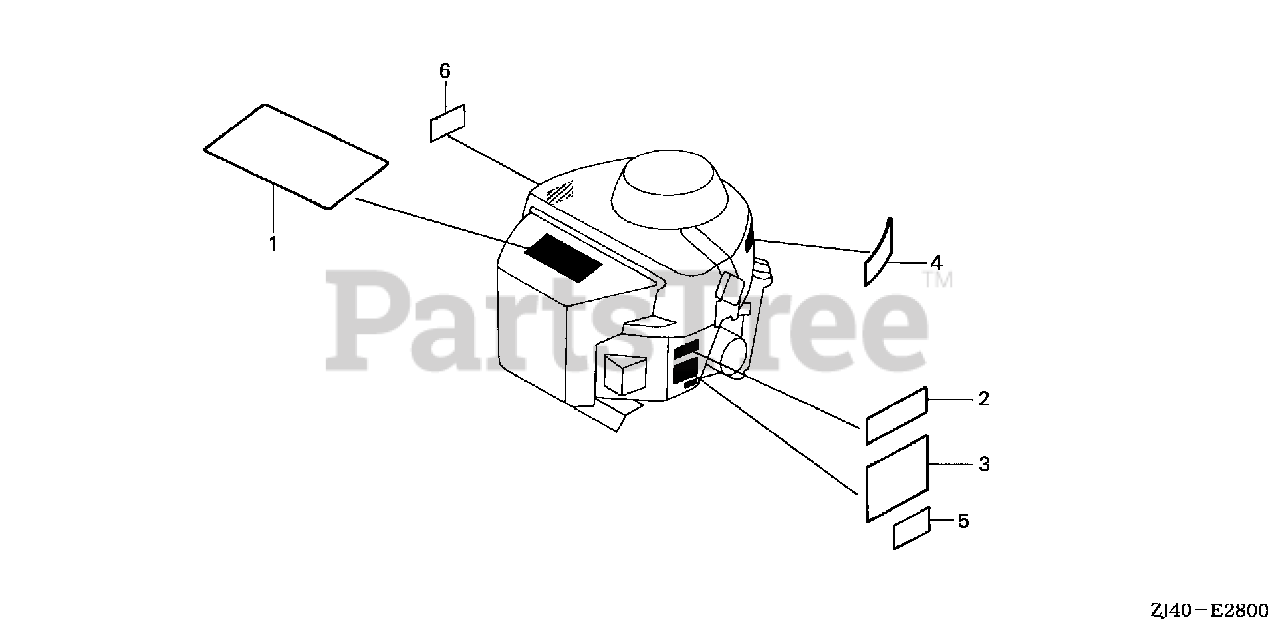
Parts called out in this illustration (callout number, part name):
1	EMBLEM (GXV610)
2	LABEL, SPECIFICATION (GXV610)
3	LABEL, CAUTION
5	LABEL, FUEL CAUTION
